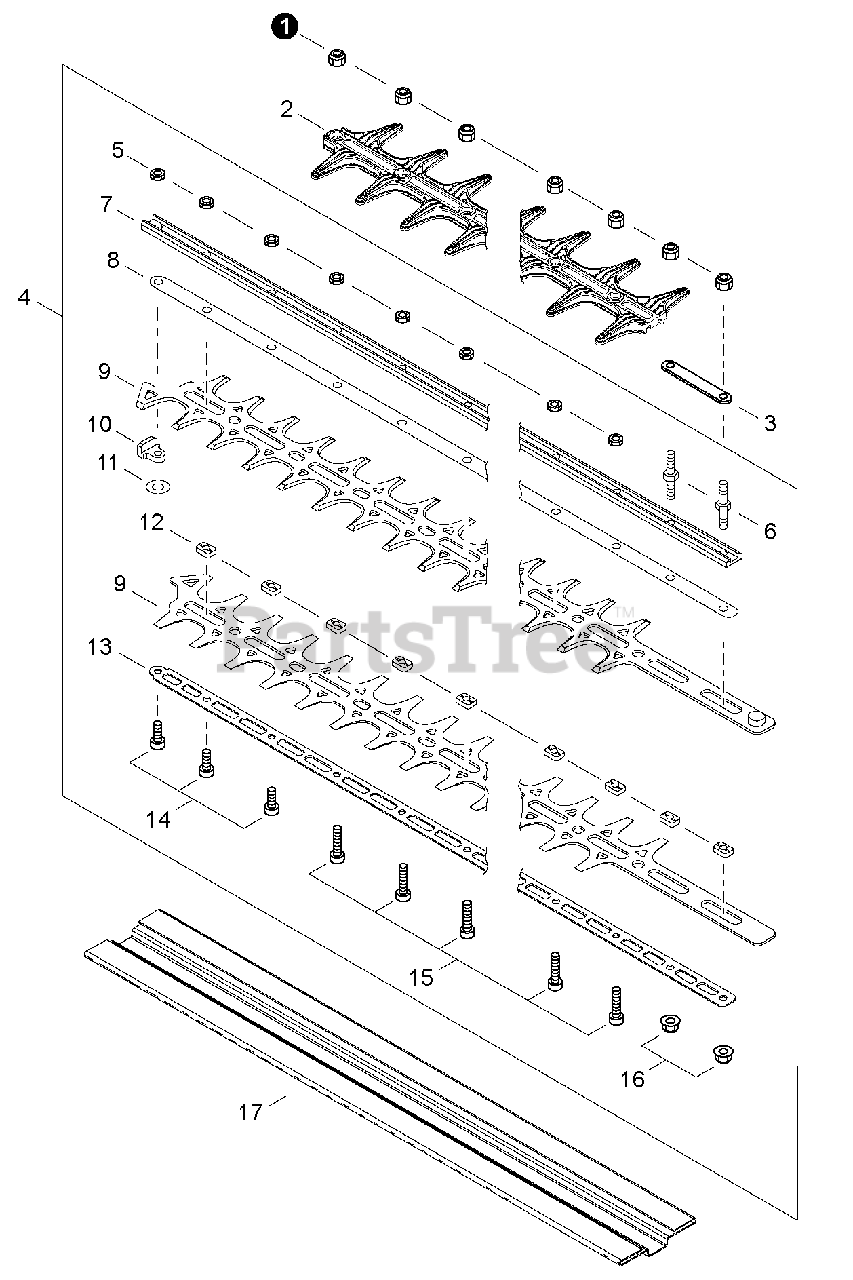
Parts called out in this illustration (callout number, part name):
1	NUT - 5
2	SUPPORT, BLADE
4	BLADE ASSY - 30" (76cm)
7	SUPPORT, CUTTER - 30" (76cm)
8	SUPPORT, CUTTER - 30" (76cm)
9	BLADE - 30" (76cm)
13	SUPPORT, BLADE - 30" (76cm)
14	SCREW - 5X16
15	SCREW - 5X25
16	NUT - 5
17	COVER, BLADE
